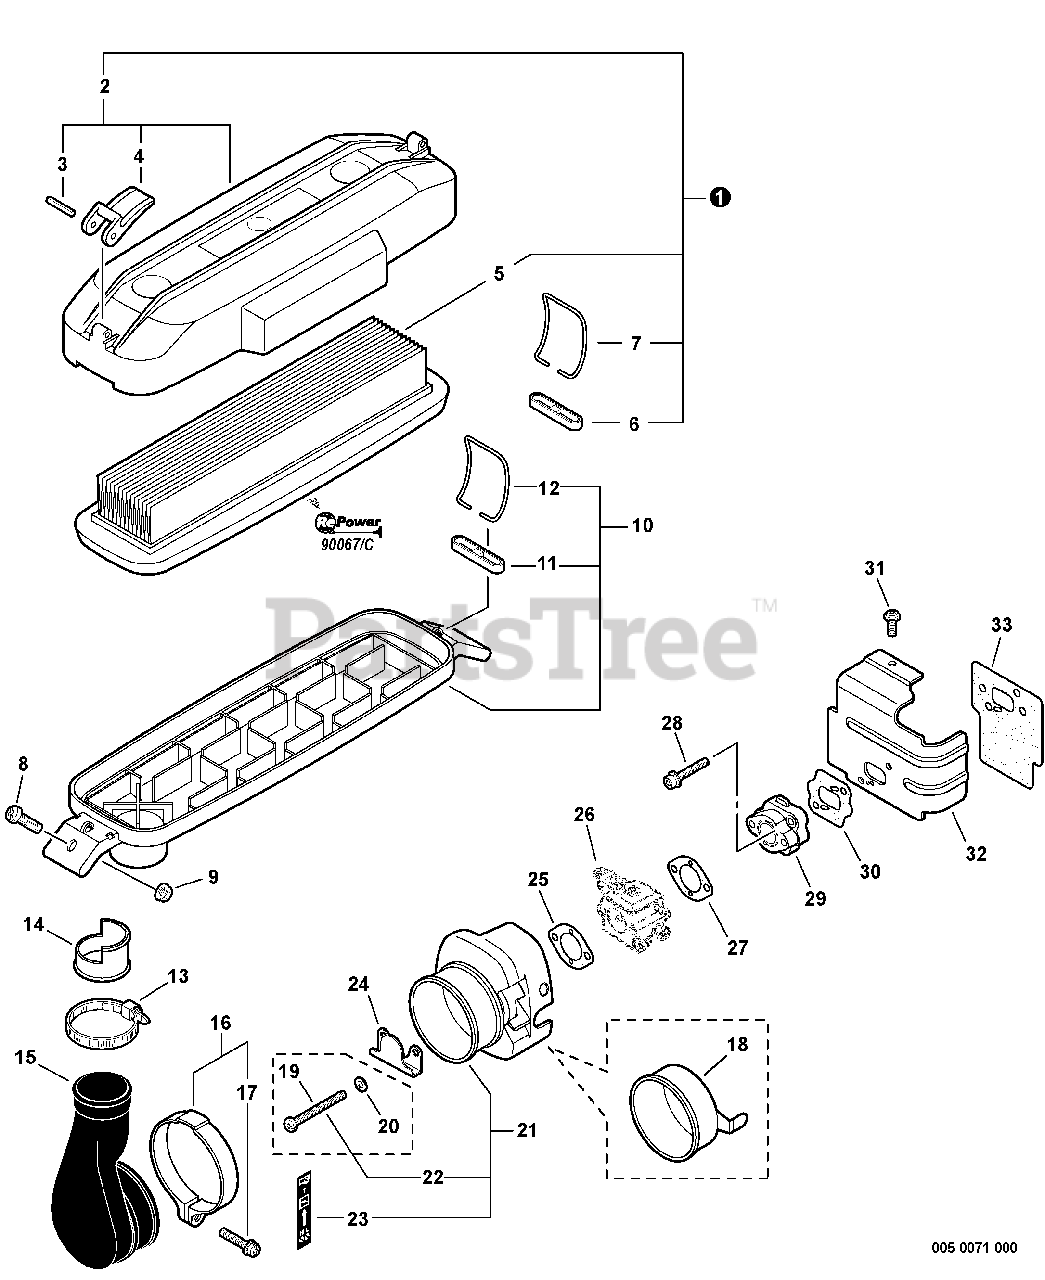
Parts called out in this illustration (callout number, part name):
1	AIR FILTER KIT
2	COVER ASSY, AIR FILTER
3	PIN, SPRING 3×25
5	FILTER, AIR
8	SCREW 5×14
9	NUT, FLANGE M5
10	CASE ASSY, AIR FILTER
14	COLLAR 27
15	ADAPTOR, INTAKE
16	CLAMP KIT
17	SCREW 5×25
19	SCREW 5×50
20	WASHER 6.5×11.5×0.8
21	BRACKET KIT, AIR FILTER
22	SCREW 5×57
23	LABEL, CHOKE
24	PLATE, PREVENT
25	GASKET, INTAKE
26	CARBURETOR
27	GASKET
28	BOLT 5×25
29	INSULATOR, INTAKE
30	GASKET, INTAKE
31	SCREW 5×10
31	TUNE-UP KIT
32	COVER, CYLINDER
33	HEAT SHIELD, INTAKE
34	TUNE-UP KIT
